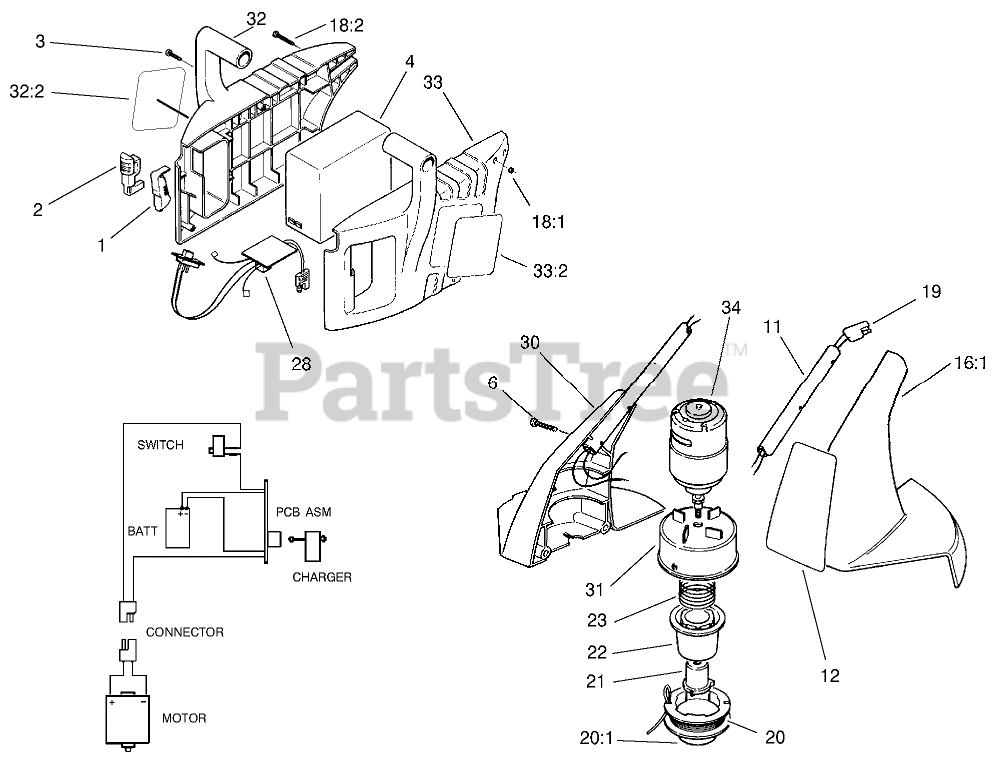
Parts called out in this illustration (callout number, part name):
1	TRIGGER
2	LOCK-TRIGGER
3	SCREW-PPH
4	BATTERY
6	SCREW-PLASTITE
11	HANDLE-EXTENSION
12	DECAL-HOUSING
16:1	HOUSING-LH
18:1	NUT-HEX
18:2	SCREW-PPH
19	WIRING HARNESS-LOWER
20	Spool-Prewound
20:1	CAP-SPOOL
21	DRIVER
22	CORE - SPOOL
23	SPRING-COMPRESSION
28	PCB ASM
30	HOUSING ASM-RH
31	DRUM ASM-4 BLADE
32	BATTERY CASE ASM-LH
32:2	DECAL-WARNING
33	BATTERY CASE ASM-RH
33:2	DECAL-BATTERY CASE
34	MOTOR ASM
